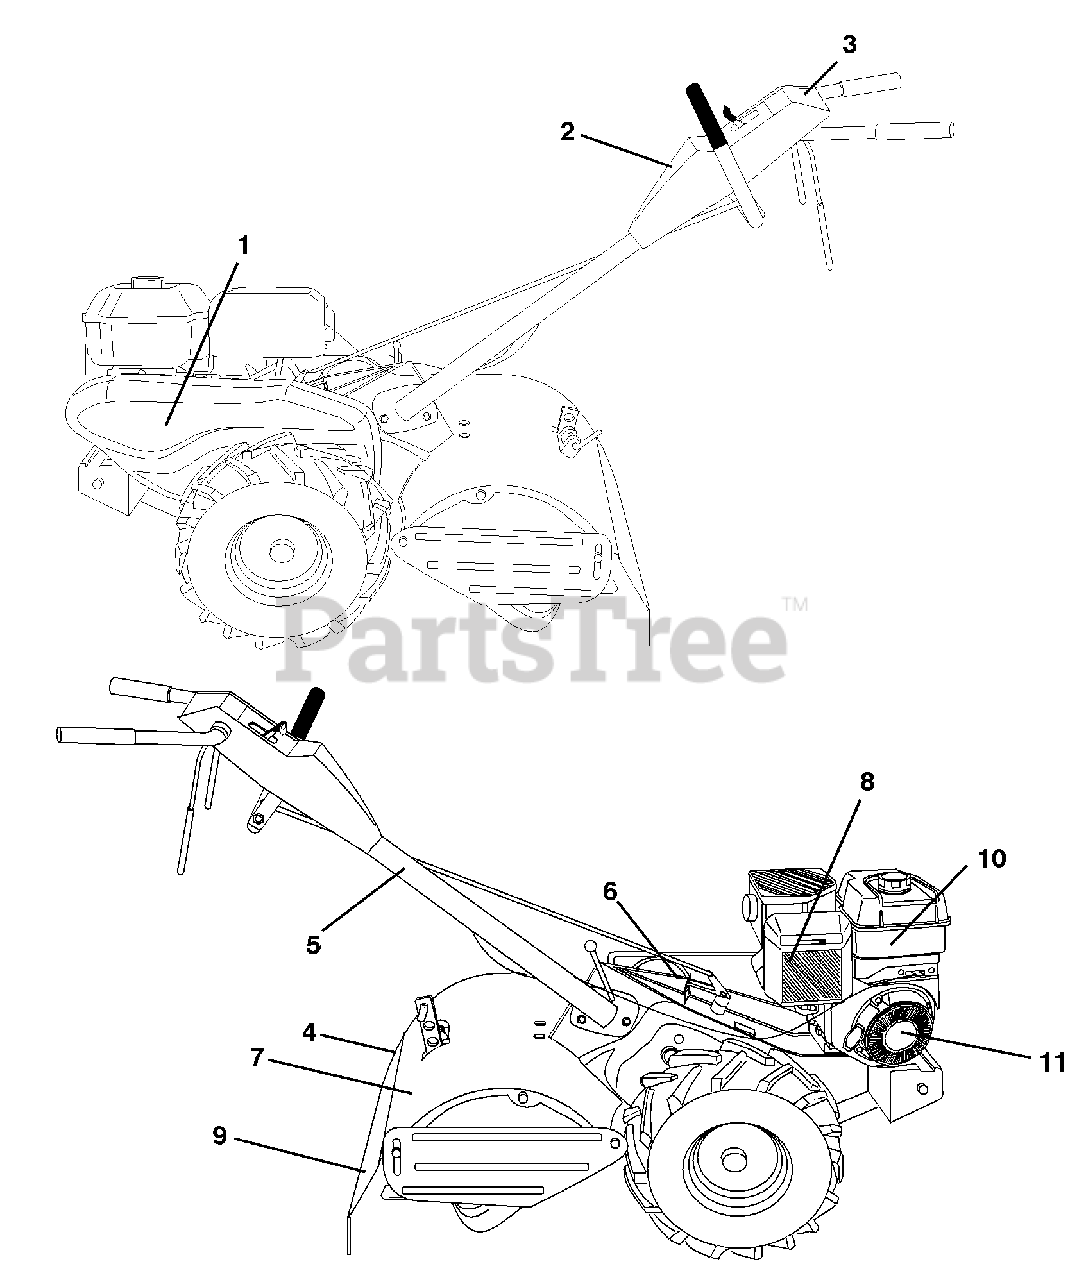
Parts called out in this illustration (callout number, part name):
1	Decal, Belt Guard
2	Decal, Husqvarna, Control Panel
3	Decal, Control Tine
4	Decal, Tine Shield
5	Decal, Hand Placement
6	Decal, Shift Indicator
7	Decal, Warning
8	Decal, Engine, 8.5
9	Decal, Warning, Rotating Tines
10	Decal, Engine, Fuel Tank, 8.5
11	Decal, Rewind Starter, B&S
